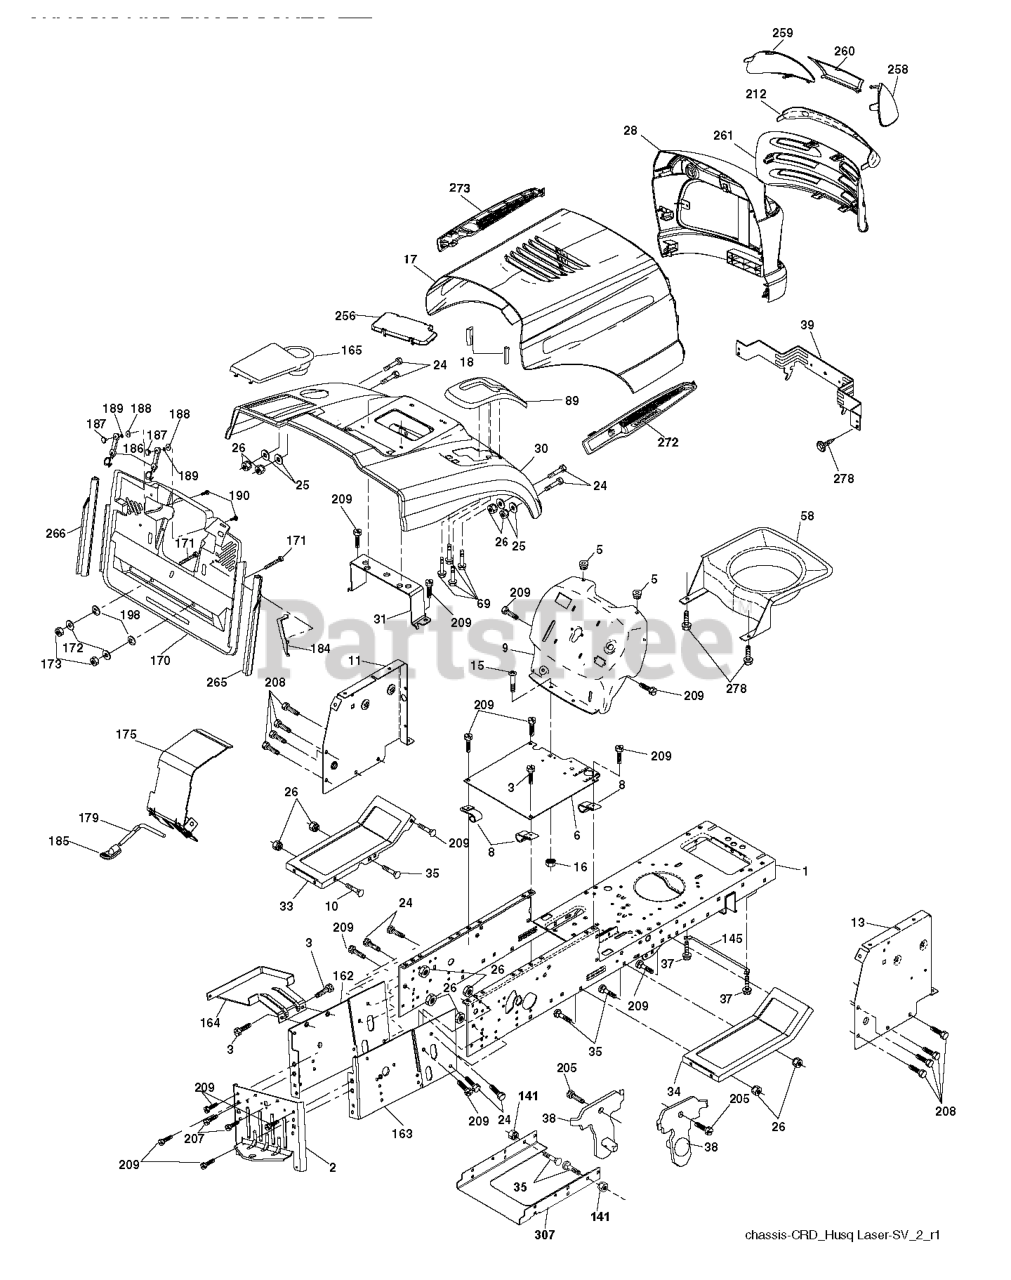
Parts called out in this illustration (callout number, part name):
2	DRAWBAR
3	SCREW 3/8-16X3/4
5	BUMPER.RUBBER.HOOD
6	PLATE
8	CLIP,INSULATOR
9	DASH.SLK.LT.PL.CC.NA.NHM.CE
10	BOLT D
11	PANEL.DASH.LH.LTX
13	PANEL ASM, DASH RH
15	Screw, Machine, Truss Head 5/16-18 UNC x 3/4
16	NUT
17	VENT.HOOD.LASER.III
18	BUMPER.HOOD.LARGE.1.75"
25	WASHER
26	NUT
30	CONSOLE.CRD.AUTO.GRY
31	BRACKET SUPPORT FENDER
33	FOOTREST.PNT.LH.BLACK
34	FOOTREST, RH
37	Screw 5/16-18 x 1/2 Hex, Self Tapping 5/16-18 x 1/2
38	BRACKET ASM PIVOT MOWER REAR
39	BRACKET PIVOT
69	SCREW.HI-LO.CONSOLE
89	CONSOLE.CRD.6SP.BLACK
141	NUT LOCK FLG 3/8-16 UNC
145	ROD.PIVOT.HOOD
162	BRACKET
163	BRACKET EXTEN CHASSIS RH CRD
165	COVER.BATTERY.CRD.BLACK
172	WASHER
175	DOOR TRAP
179	ROD PIVOT FBI
184	BRACKET.ACTUATOR.BAGGER.SRD
186	LATCH ASSY
187	WELDNUT
189	LOCKWASHER #10
190	SCREW
207	SCREW, 5/16-18 X 1/2
208	SCREW 3/8-16X1/2
209	SCREW, 3/8-16X3/4
212	INSERT.LENS.REFLECTIVE
256	COVER FENDER CRD
258	LENS LH
259	LENS LH
260	COVER.LENS.HUSQ.LASER
265	SEALING
266	SEALING
272	VENT.HOOD.LASER.
273	VENT.HOOD.LASER.
278	SCREW.#10 X 0.750.BOS
